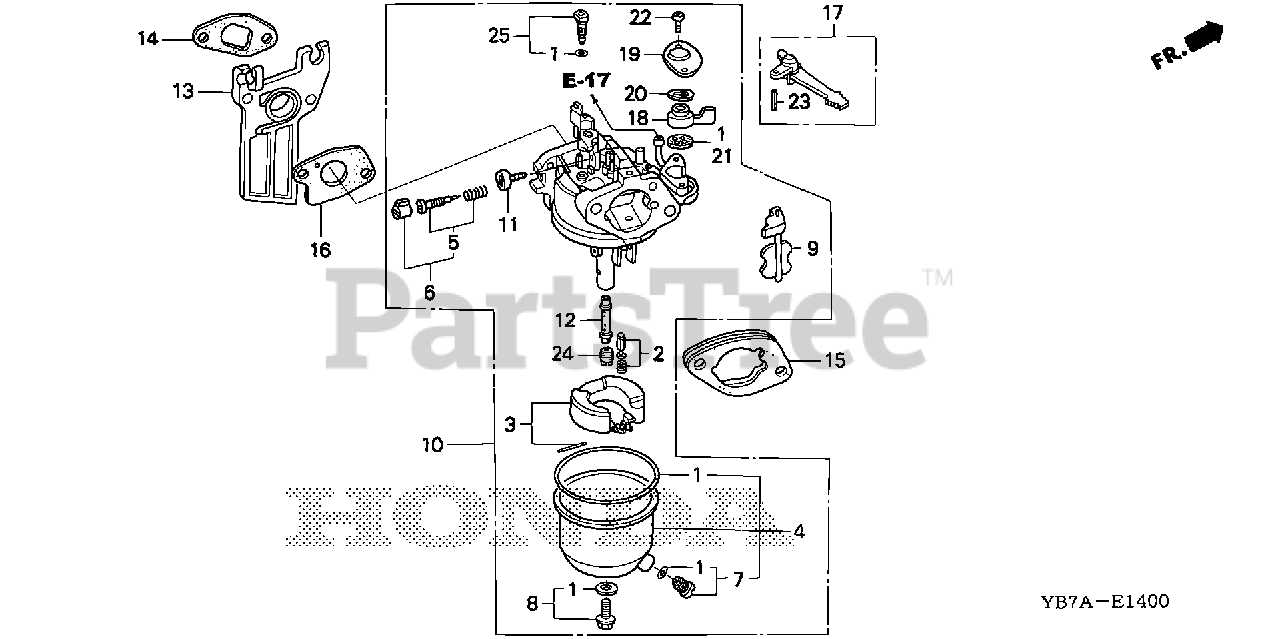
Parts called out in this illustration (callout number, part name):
1	GASKET SET (CARBURETOR NO.)
2	VALVE SET, FLOAT (SEAT NOT INCLUDED)
4	CHAMBER SET, FLOAT
6	SCREW SET, PILOT (CARBURETOR NO.)
7	SCREW SET, DRAIN
9	CHOKE SET (CARBURETOR NO.)
10	CARBURETOR ASSY. (BE61M A)
11	SCREW, THROTTLE STOP
12	NOZZLE, MAIN
13	INSULATOR, CARBURETOR
14	GASKET, INSULATOR
15	SPACER, CARBURETOR
16	GASKET, CARBURETOR
17	LEVER, CHOKE (STD)
18	LEVER, PETCOCK
19	PLATE, LEVER SETTING
20	SPRING, PETCOCK LEVER
21	GASKET, PETCOCK (CARBURETOR NO.)
22	SCREW, PAN (3X6)
23	PIN, SPRING (2X12)
24	JET, MAIN (#58)
24	JET, MAIN (#60)
24	JET, MAIN (#62)
25	JET SET, PILOT (#35) (CARBURETOR NO.)
